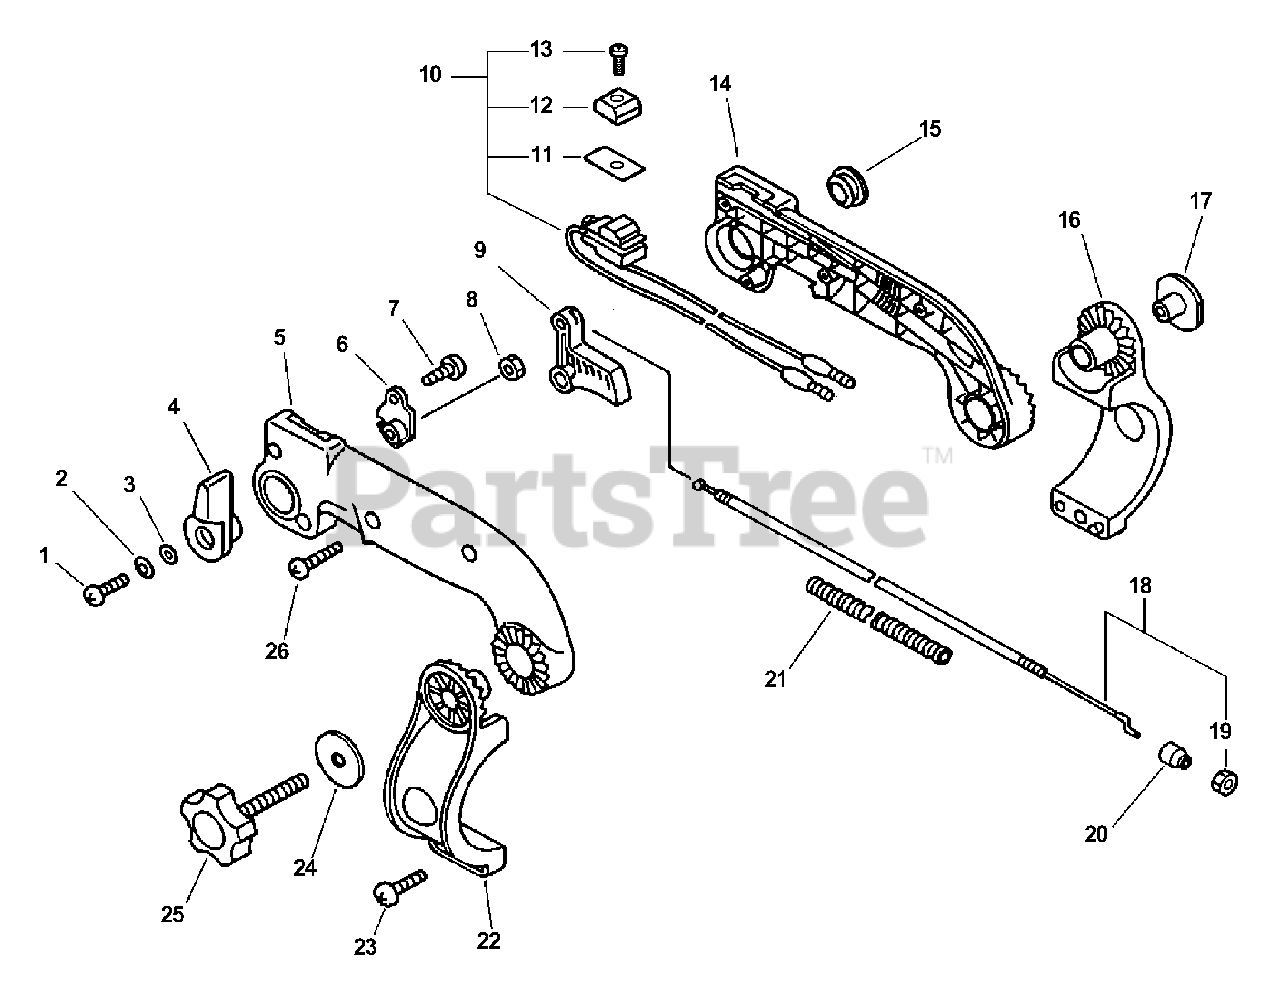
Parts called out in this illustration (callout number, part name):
1	SCREW - 6X20
2	LOCKWASHER - 6
3	WASHER - 6
4	CONTROL, THROTTLE
5	HANDLE, CONTROL - LEFT
6	BRACKET, THROTTLE
7	SCREW - 4X10
8	LOCKNUT - 6
9	TRIGGER, THROTTLE
10	IGNITION SWITCH ASSY
11	COVER, SWITCH - STOP
12	KNOB, SWITCH - ORANGE
13	SCREW - 3X10
14	HANDLE, CONTROL - RIGHT
16	BRACKET, HANDLE - RIGHT
18	CABLE, THROTTLE
19	LOCKNUT - 6
20	CAP, DUST
21	TUBE, PROTECTIVE - CORRUGATED
22	BRACKET, HANDLE - LEFT
23	SCREW - 5X20 -- TAPPING
24	WASHER - 6
25	THUMBSCREW
26	SCREW - 4X22
